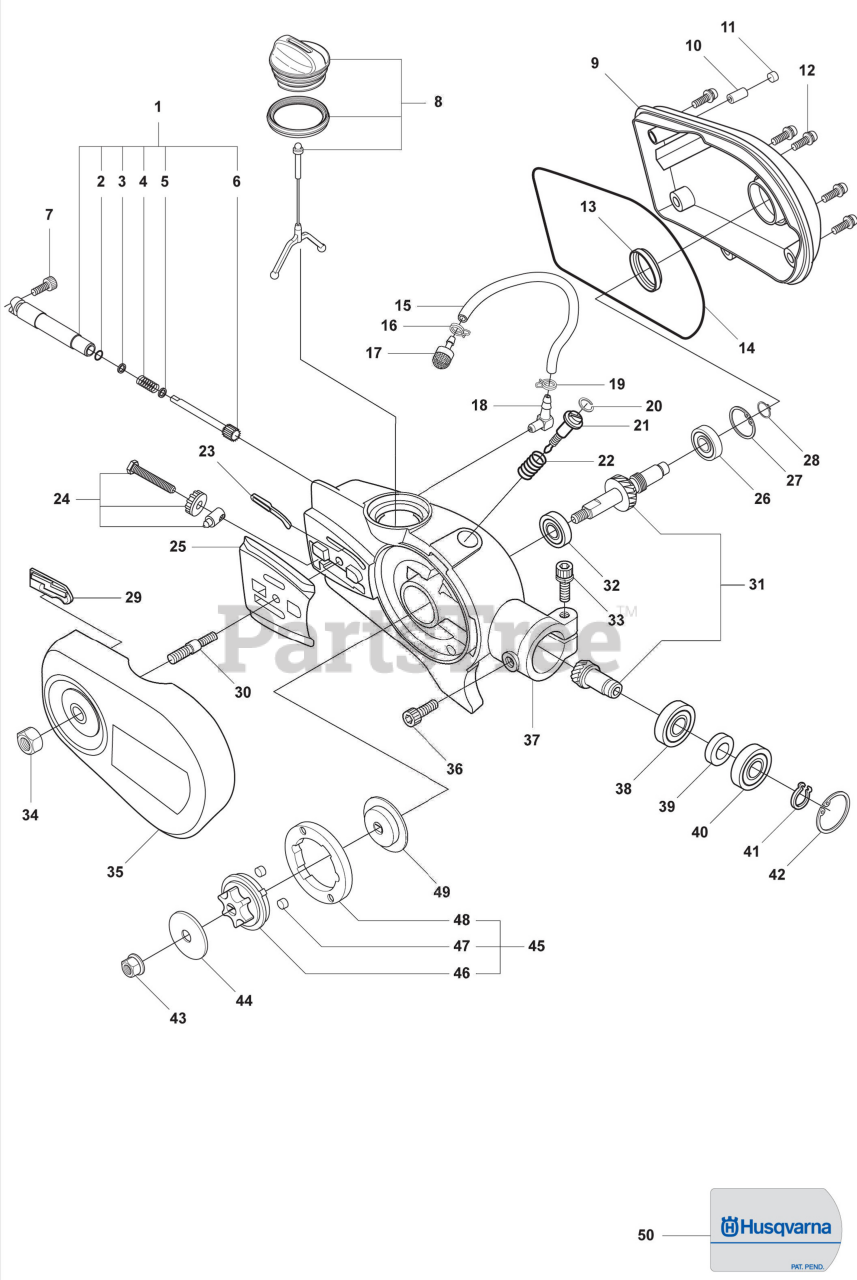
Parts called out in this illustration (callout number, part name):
1	Oil Pump
2	O-Ring, 5.1 X 1.6 NITRILE
3	Washer, 5.1 X 8.5
4	Spring
5	Washer, 5.1 X 8.5
6	Pump Piston
7	Screw, MC6S 5 X 12
8	Oil Tank Cap, Grey
9	COVER
10	Valve
11	Plug
12	Screw, MC6S 5 X 16
13	Ring
14	O-Ring
15	HOSE
16	Clip
17	Oil Plummet
18	NIPPLE
19	Clip
20	Retaining Ring
21	Screw
22	Spring
23	Sealing
24	Chain Tensioner
25	Plate
26	Ball Bearing
27	Retaining Ring
28	Snap Ring
29	Sealing Plate
30	Bolt
31	GEAR
32	Ball Bearing
33	Screw, MC6S 5 X 25
34	Hex Nut
35	Cover
36	Screw, MC6S 5 X 12
37	Housing
38	Ball Bearing
39	SPACER SLEEVE
40	Ball Bearing
41	Retaining Ring
42	Retaining Ring
43	Hex Flange Nut
44	Fender Washer
45	Sprocket Kit
46	Sprocket
47	Vibration Absorber
48	FLYWHEEL
49	Cover
50	DECAL
